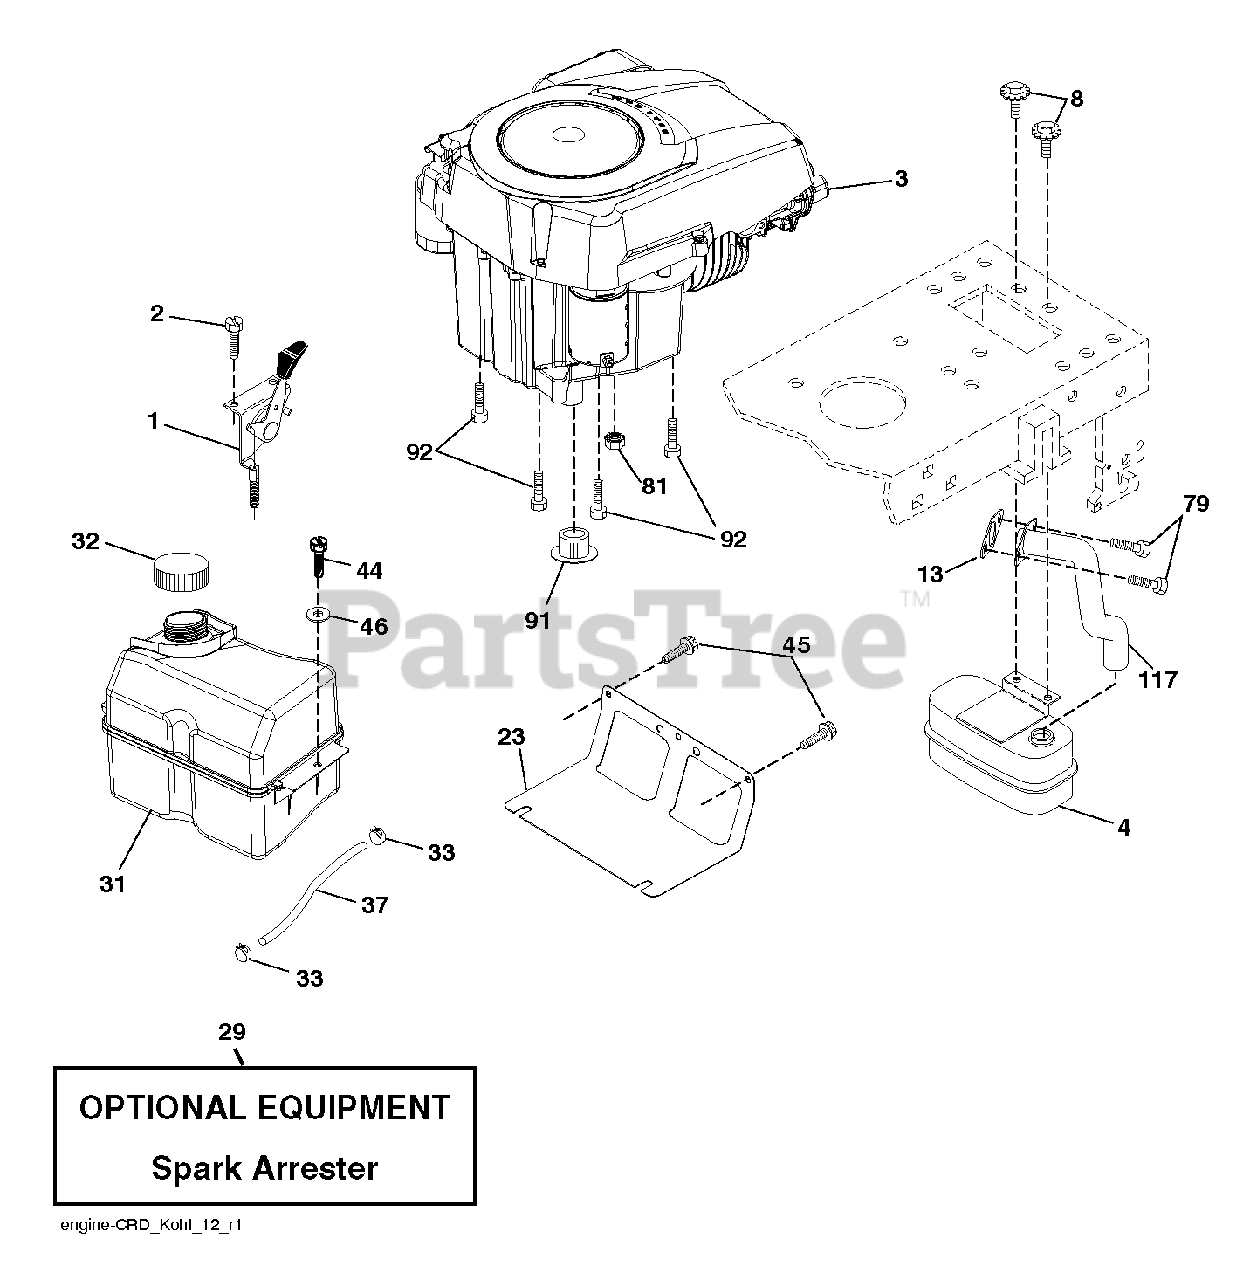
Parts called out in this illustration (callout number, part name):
1	CONTROL.TH/CK.C.
2	SCREW.#10 X 0.750.BOS
4	MUFFLER.SINGLE.CYL.KOHL/B&S
8	BOLT, 5/16-18 X 1 3/4
13	GASKET.EXHAUST.KOHLER
23	SHIELD.BROWNING.DBR.GUARD
29	KIT.SPARK ARRESTOR 794945 B&S
31	RP TANK FUEL FRT 1.5 GAL
32	CAP ASM.FUEL.2.25"FR.
33	HOSE CLAMP
37	LINE.FUEL.20
44	SCREW HEXWSHR 1/4-20X3/4
45	SCREW, 3/8-16X3/4
79	SCREW.SOCKET HD.5/16-1
81	NUT
91	BUSHING.1.375OD
92	SCREW 3/8-16X1
117	RP.TUBE.EXHAUST.KOHL.COURAGE
